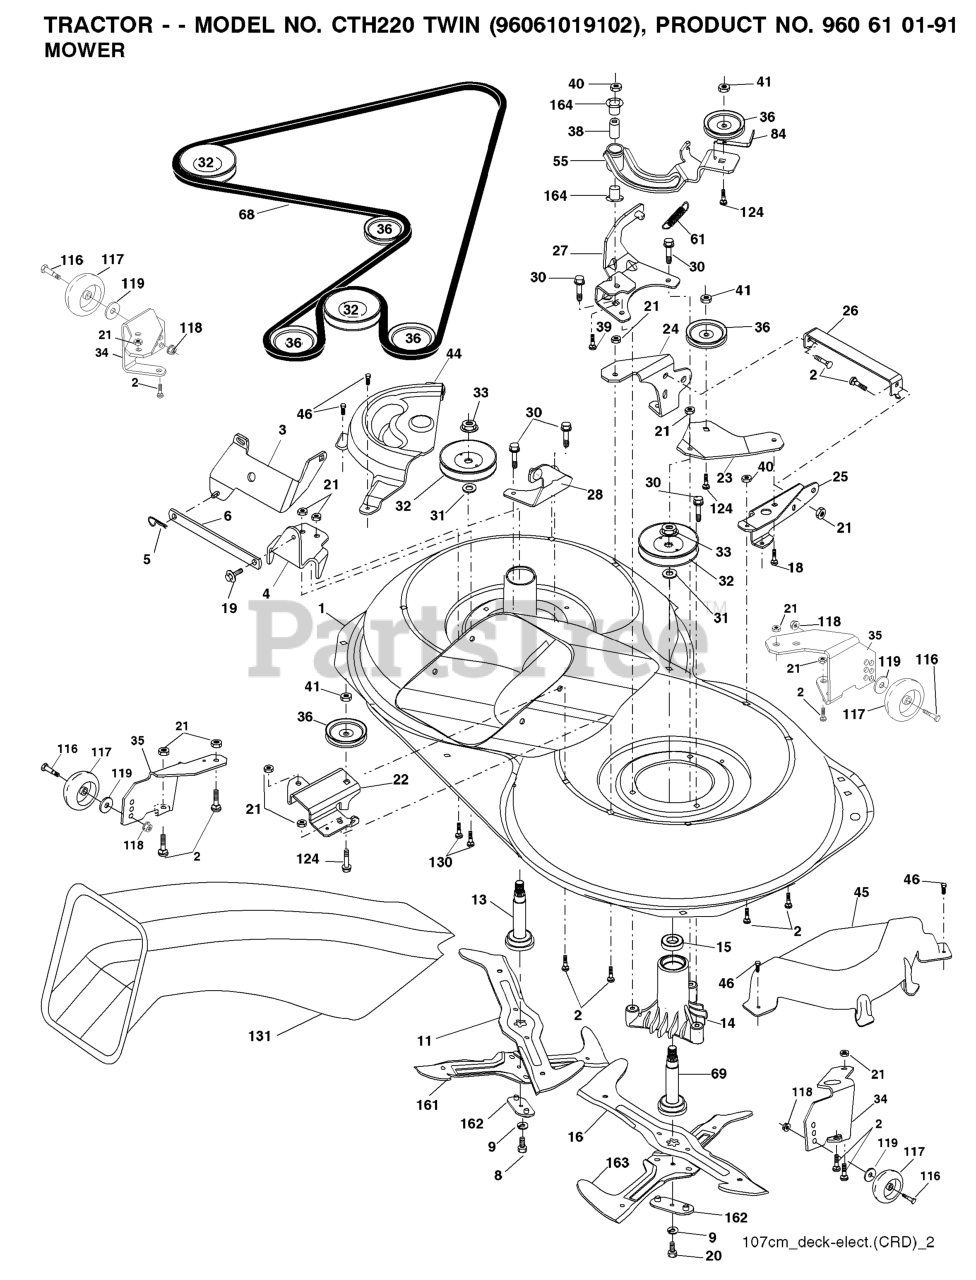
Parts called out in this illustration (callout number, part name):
1	Housing Asm. Mower 107 CRD
2	RP BOLT 5/16-18 X3/4 ZN/YEL GR
5	RETAINER-SPRNG RB
6	BAR.SWAY.92.CRD
8	BOLT.3/8-24X1.25 GR8
9	LOCKWASHER
11	BLADE.3N1.LH.CRD
13	SHAFT ASM VENT
14	HOUSING.MANDREL.VENTED (MACHD)
16	BLADE.3N1.RH.CRD
19	BOLT SHD 5/16-18
20	BOLT.3/8-24X1.25GR8. LHTHRD
21	LOCKNUT
22	BRACKET.IDLER.RR.107.CRD
24	BRACKET
25	BRACKET RF
26	SUPPORT
28	BRACKET
30	SCREW, WASHER HEAD
31	WASHER.SPACER.MANDREL
32	PULLEY.MANDREL.4.80 PD.2006
33	NUT.FLANGE.LOCK.TOP
34	BRACKET
35	BRACKET
36	PULLEY.IDLER.4.25
41	NUT LOCK FLG 3/8-16 UNC
45	COVER.MANDREL.RH.CRD
46	SCREW.1/4-20X5/8
55	ARM.IDLER.107.CRD
61	SPRING
68	HEX-BELT 107 MOWER
69	SHAFT.ASM.W/LWR.BRG.RH.THREAD
84	KEEPER, BELT IDLER
116	BOLT.SHOULDER.3/8-16X3-5/8.
117	RP WHEEL. GUAGE RALLY
118	NUT LOCK FLG 3/8-16 UNC
119	WASHER
124	BOLT.3/8-16X1.50
130	BOLT.CARR.SQNK.5/16-18UNC.X3/4
131	CHUTE BAGGER
163	BLADE.CROSS.RH.CRD.107
164	BRNG T
